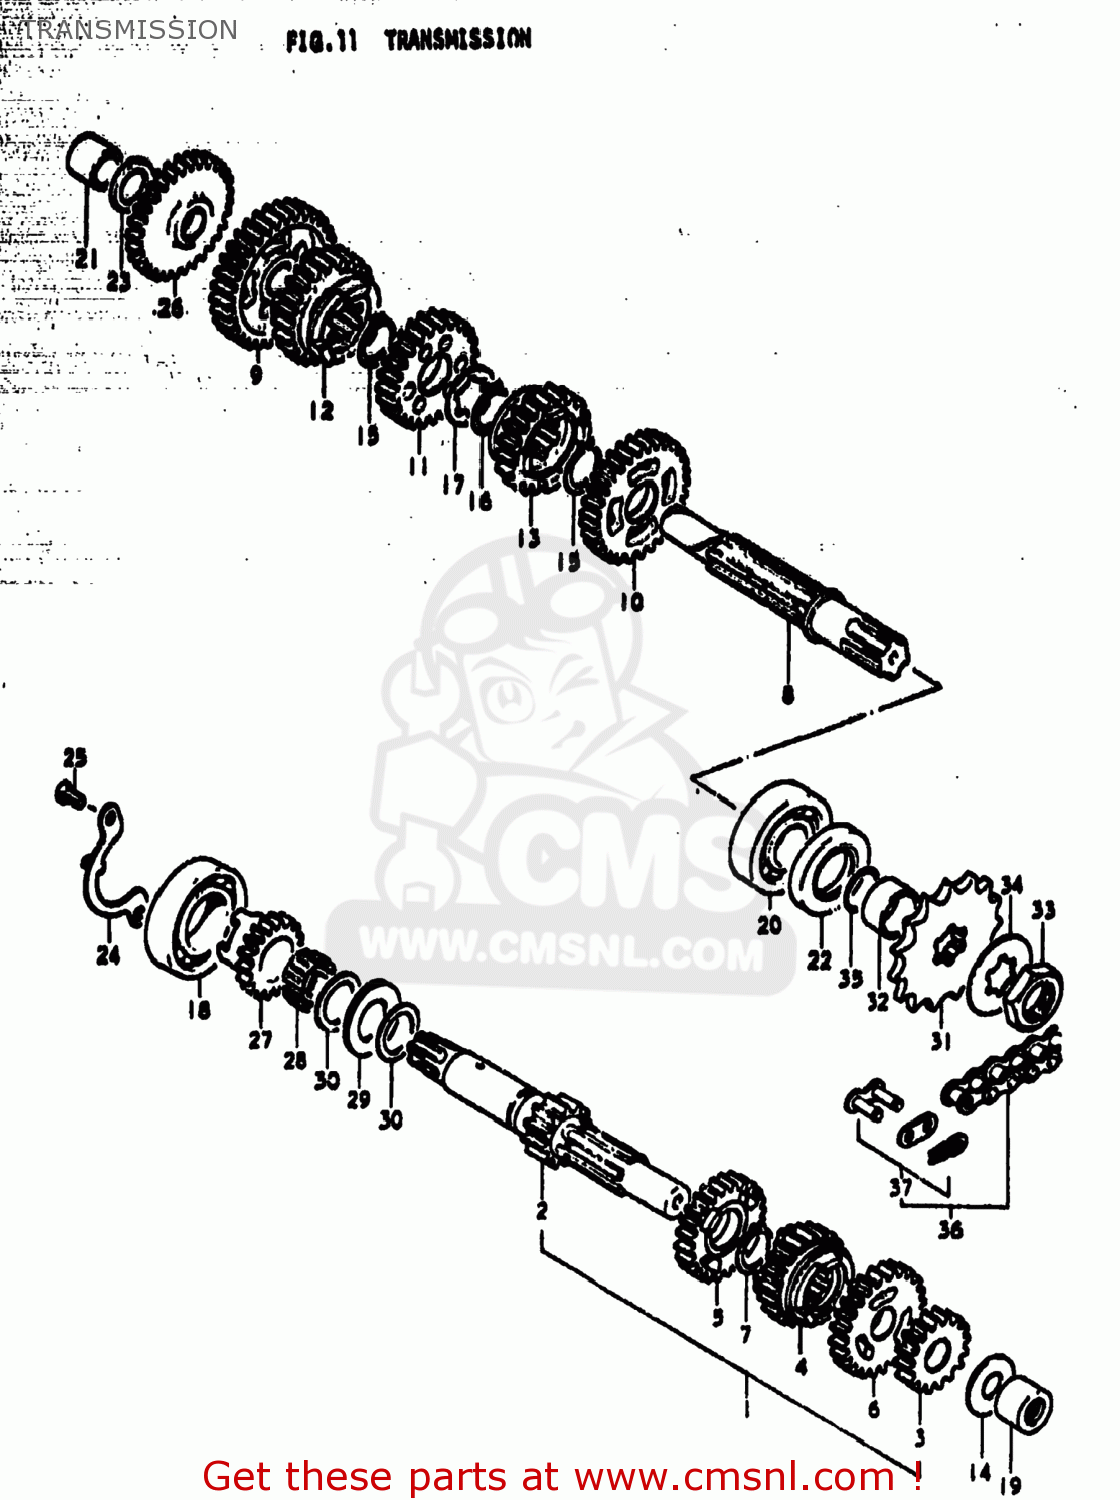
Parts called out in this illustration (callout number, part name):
1	SHAFT,COUNTER
2	SHAFT,COUNTER
3	GEAR,2ND DRIVE
4	GEAR,3RD DRIVE
5	GEAR,FOURTH DRIVE
6	GEAR,5TH DRIVE
7	CIRCLIP
8	SHAFT,DRIVE
9	GEAR,1ST DRIVEN
10	GEAR,2ND DRIVEN
11	GEAR,THIRD DRIVEN
12	GEAR,FOURTH DRIVEN
13	GEAR,FIFTH DRIVEN
14	WASHER
15	CIRCLIP
16	CIRCLIP
17	WASHER
18	BEARING, RH
19	BEARING(15X22X15)
20	BEARING
21	BUSH
22	OIL SEAL (25X44X7)
23	WASHER
24	RETAINER,CNTR SHAFT BEARING
25	SCREW 6X12
26	GEAR,KICK STARTER IDLE
27	GEAR,KICK STARTER DRIVEN
28	BEARING(19.2X23.2X19)
29	BEARING(21X32X2.85)
30	WASHER(21X30X0.8)
31	SPROCKET,ENGINE
32	SPACER(20X25X12.5)
33	NUT
34	WASHER,LOCK
35	O RING(D:1,ID:19.5)
36	CHAIN ASSEMBLY,DRIVE
37	JOINT
